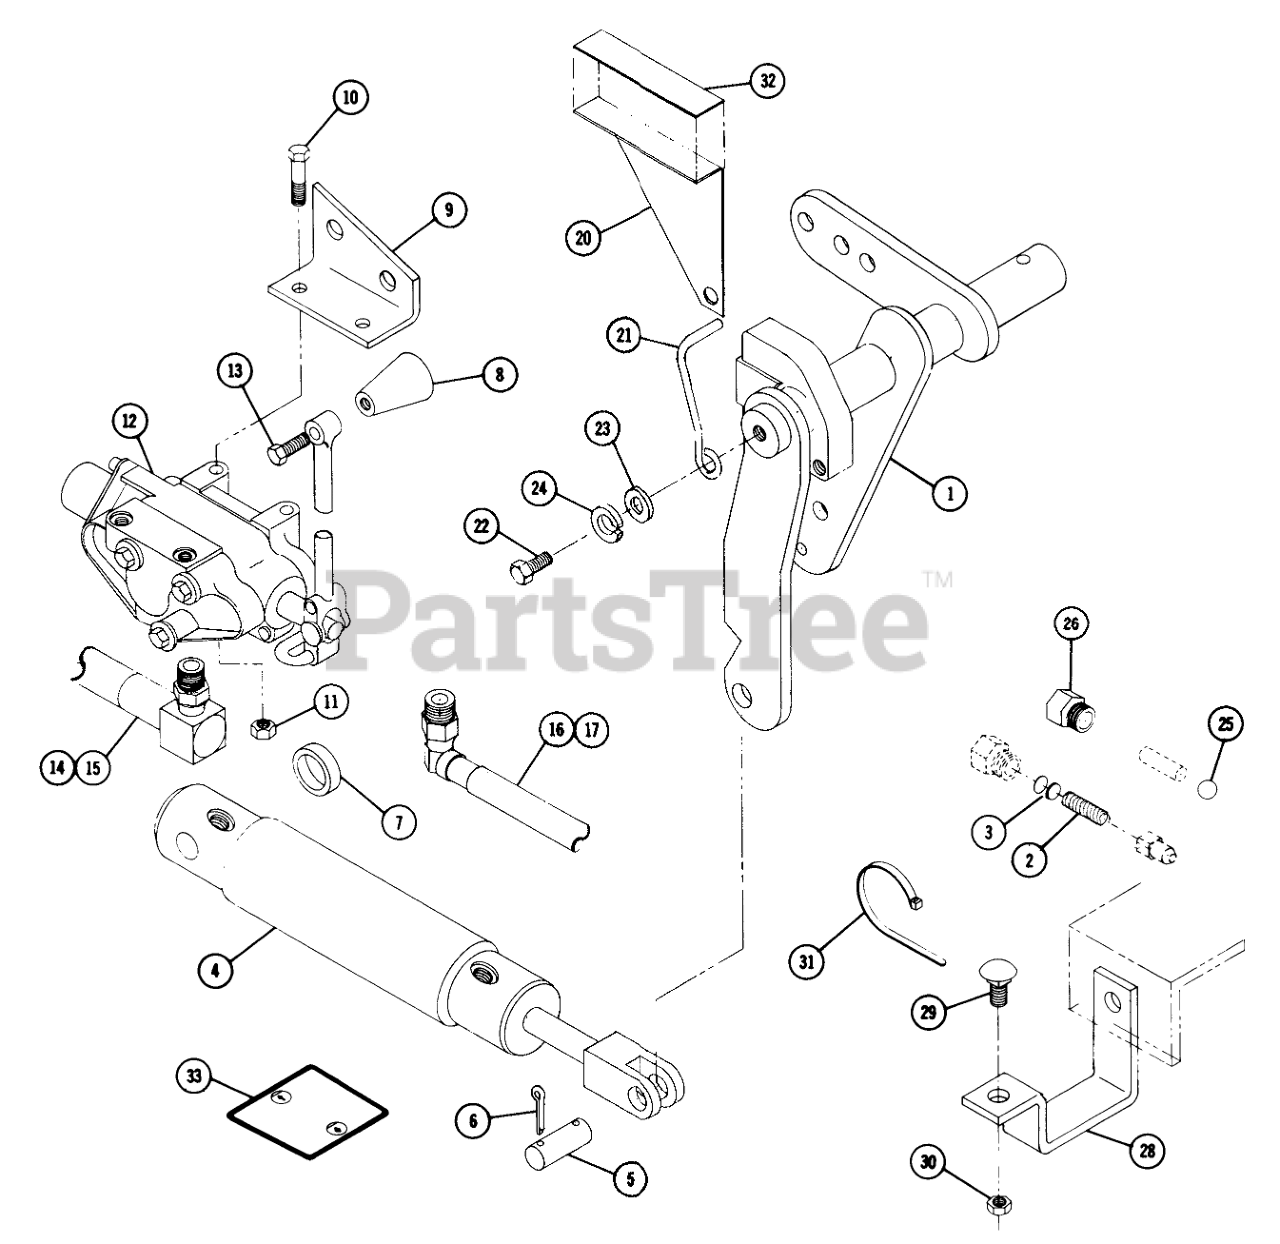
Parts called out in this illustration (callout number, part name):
1	Lift Arm
2	SPRING VALVE SUNSTR
3	Shim Set
4	Cylinder
5	PIN
7	Spacer
9	SUPPORT-VALVE
10	Bolt 1/4-20 X 1 1/2
11	Nut
12	Valve
13	SCREW
14	HOSE HYDRAULIC 19"
15	16" Hose Assembly
16	Ass-y . Hose-14 1/2
17	HYD HOSE ASSY
20	Indicator Plate
21	Arm
22	Screw
23	WASHER 5/16 SAE
24	Lockwasher
25	Ball
28	Bracket
29	Bolt-Carriage
30	Nut
31	PLASTIC TIE
32	Decal
33	DECAL-HAND LIFT
